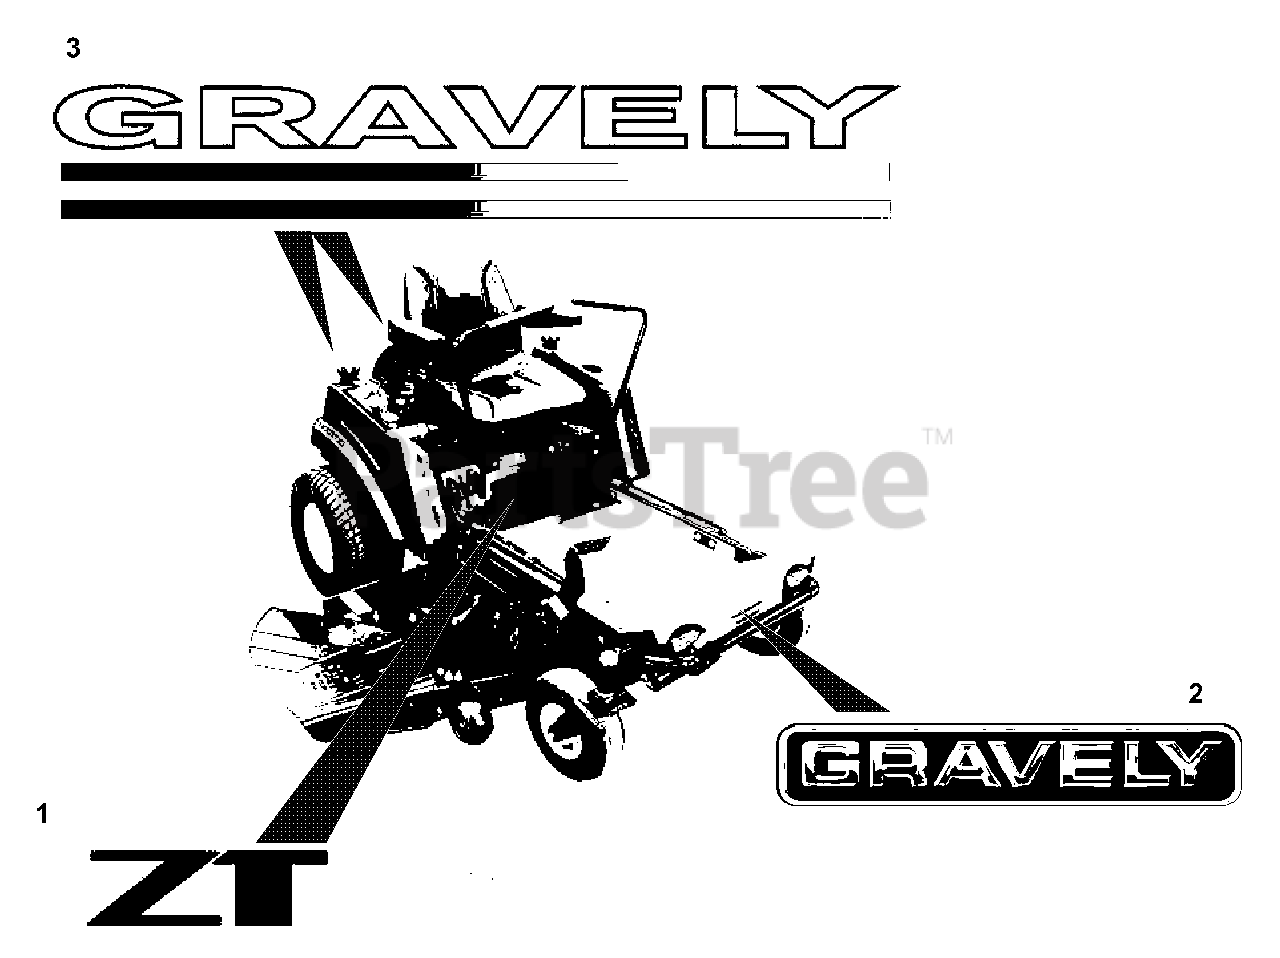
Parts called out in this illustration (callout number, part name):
1	DECAL-GRAVELY AT HOME
2	DECAL, GRAVELY LOGO
3	DECAL ZT HOOD
